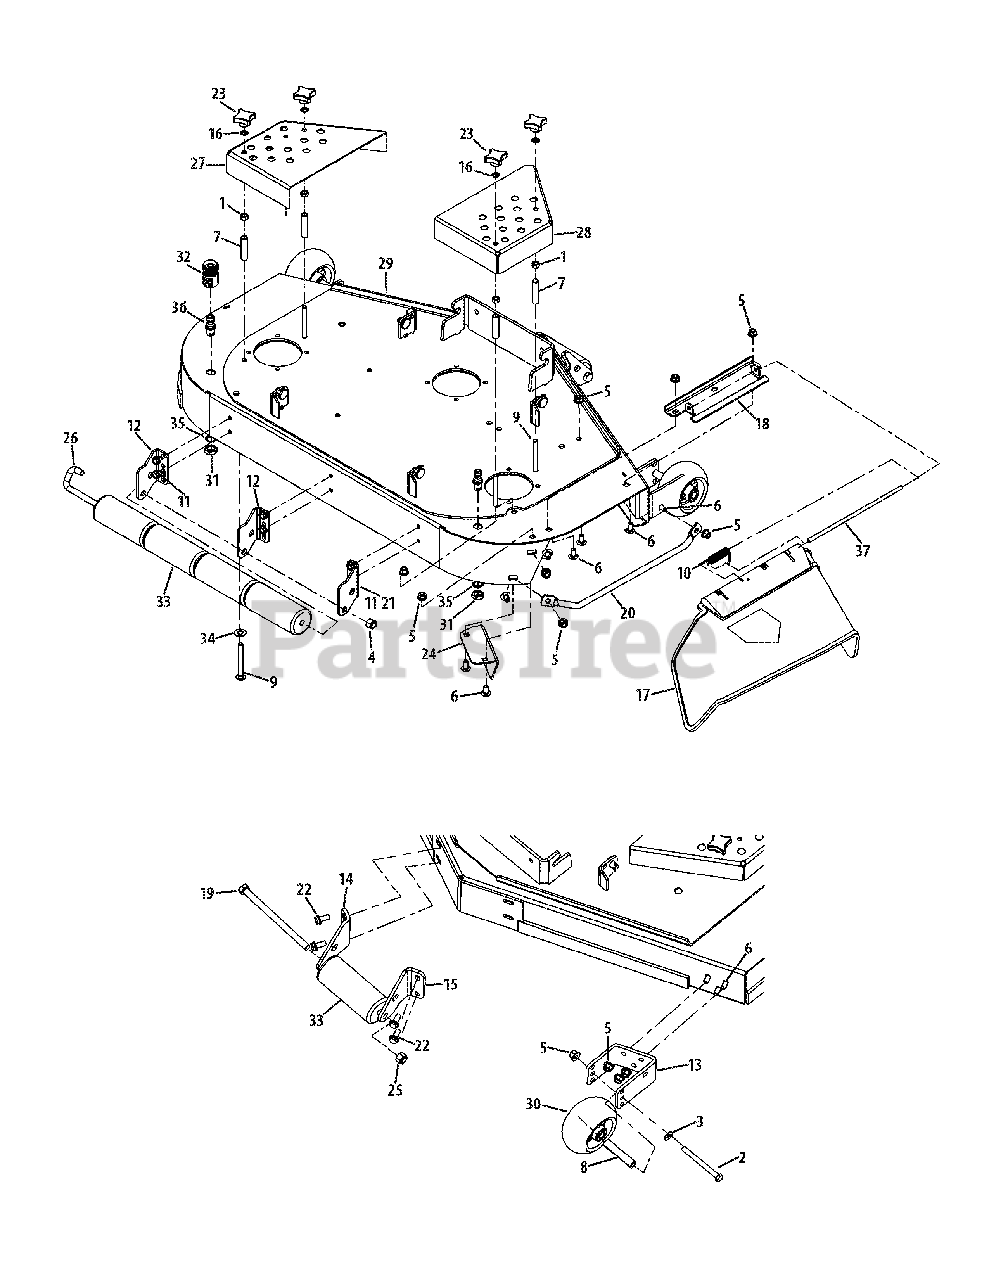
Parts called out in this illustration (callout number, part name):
1	Nut, 3/8-16
2	Hex Screw, 3/8-16 x 4.00
3	Washer, .406 x .813 x .063
4	Hex Lock Nut, 1.2-13
5	Flange Counterlock Nut, 3/8-16
6	Carriage Bolt, 3/8-16 x .75
7	Spacer, .400 x .560 x 2.45
8	Spacer, .390 x .620 x 3.04
9	Carriage Bolt, 3/8-16 x 3.50
10	Torsion Spring, .639 x 2.16 x .12
11	Flange Screw, 3/8-16 x .500
12	Roller Mount Bracket
13	Anti-Scalp Front Mount Bracket
14	LH Front Roller Mount Bracket
15	RH Front Roller Mount Bracket
16	Washer, .398 x .694 x .032
17	Chute Deflector
18	Chute Deflector Bracket
19	Hex Screw, 1.2-20 x 7.50
20	Finger Guard
21	RH Roller Mt. Brkt. (48"Inch Deck)
22	Flange Screw, 3/8-16 x .875
23	Plastic Knob, 3/8-16
24	Micro Chute Baffle
25	Nut, 1.2-20
26	J-Hook
27	LH Belt Cover
28	RH Belt Cover
29	Deck Assembly (48"Inch Deck)
29	Deck Assembly (54"Inch Deck)
31	Hex Nut
32	Water Nozzle Adapter
33	Front Roller
34	Flat Washer, .510 x 1.00 x .060
35	Lock Washer, 17 x 23.8 x 1.95
36	Water Deck Nozzle
37	Chute Deflector Rod
